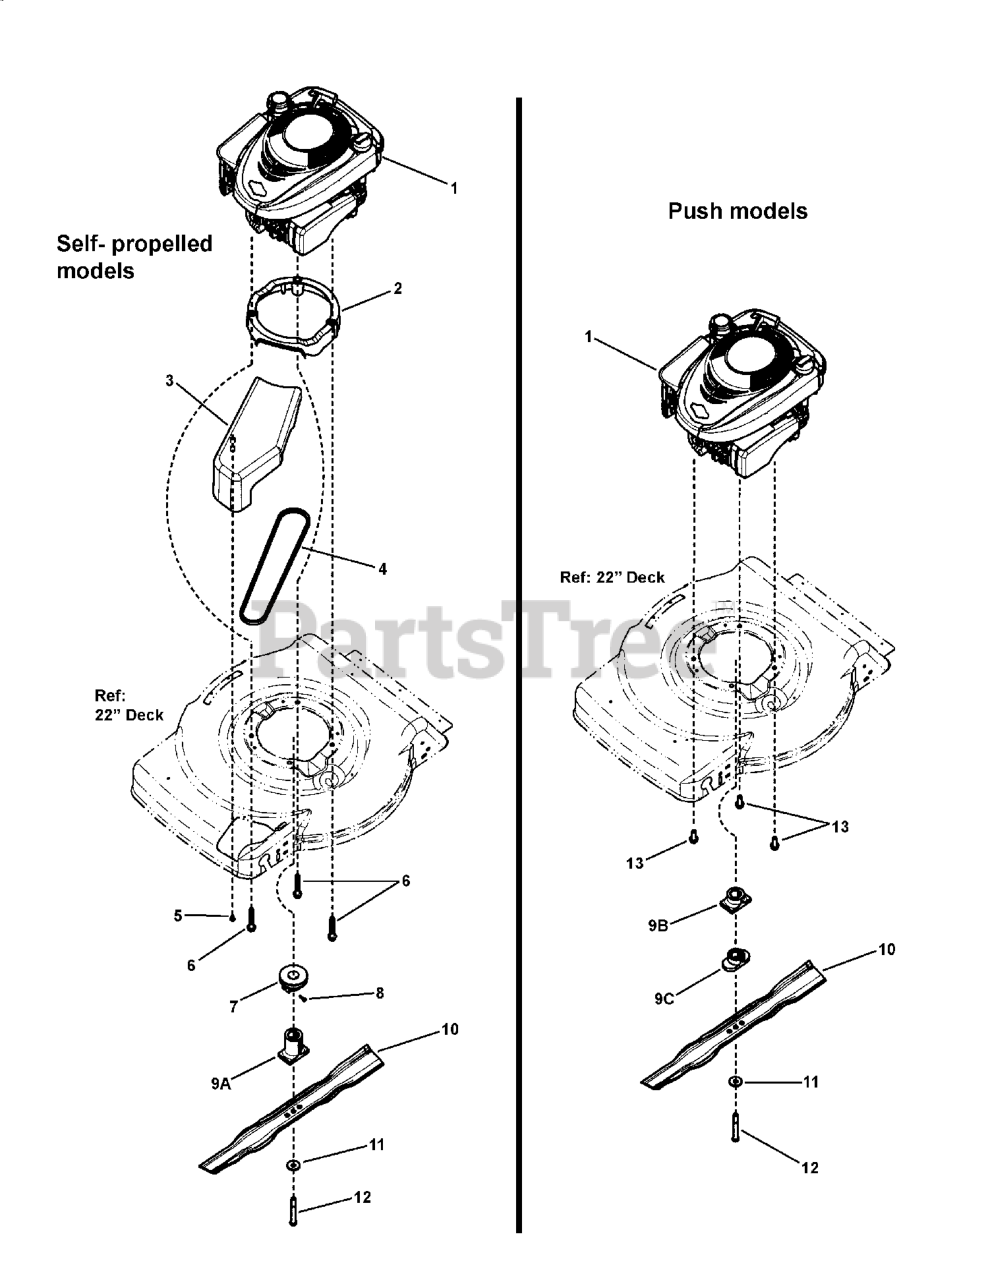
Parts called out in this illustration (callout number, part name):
1	* ENGINE, B&S, 650 Ser, B3, X-Spec
1	* ENGINE, B&S, 675 Ser, B3, X-Spec
1	* ENGINE, B&S, 550 Ser, X, B3
2	** ASSY, Engine Spacer, 22" WBM, Propelled
3	COVER, Belt, Plastic
4	BELT, Drive 22" WBM, SS (3L sect. 33.75 effective length)
5	SCREW, Hi-Lo, 4.8 x 1.59 x 13mm Round Washer Head
6	BOLT, 3/8-16 x 2-1/2" Hex Washer Face
7	PULLEY, Engine, 22" Deck, Single Speed
8	SCREW, #8-11 x 5/8" Poly
9A	HUB, Blade, 22" S. P. Deck
9B	HUB, Blade, 22" Push
9C	HUB, Blade, 22" Push
10	BLADE, 22" Walk Mower
11	WASHER, Bellville, .38" ID x 1.183 OD
12	BOLT, 3/8-24 x 3-1/4" Hex Head, GR 8
13	HWST, 3/8C X1 BZ
